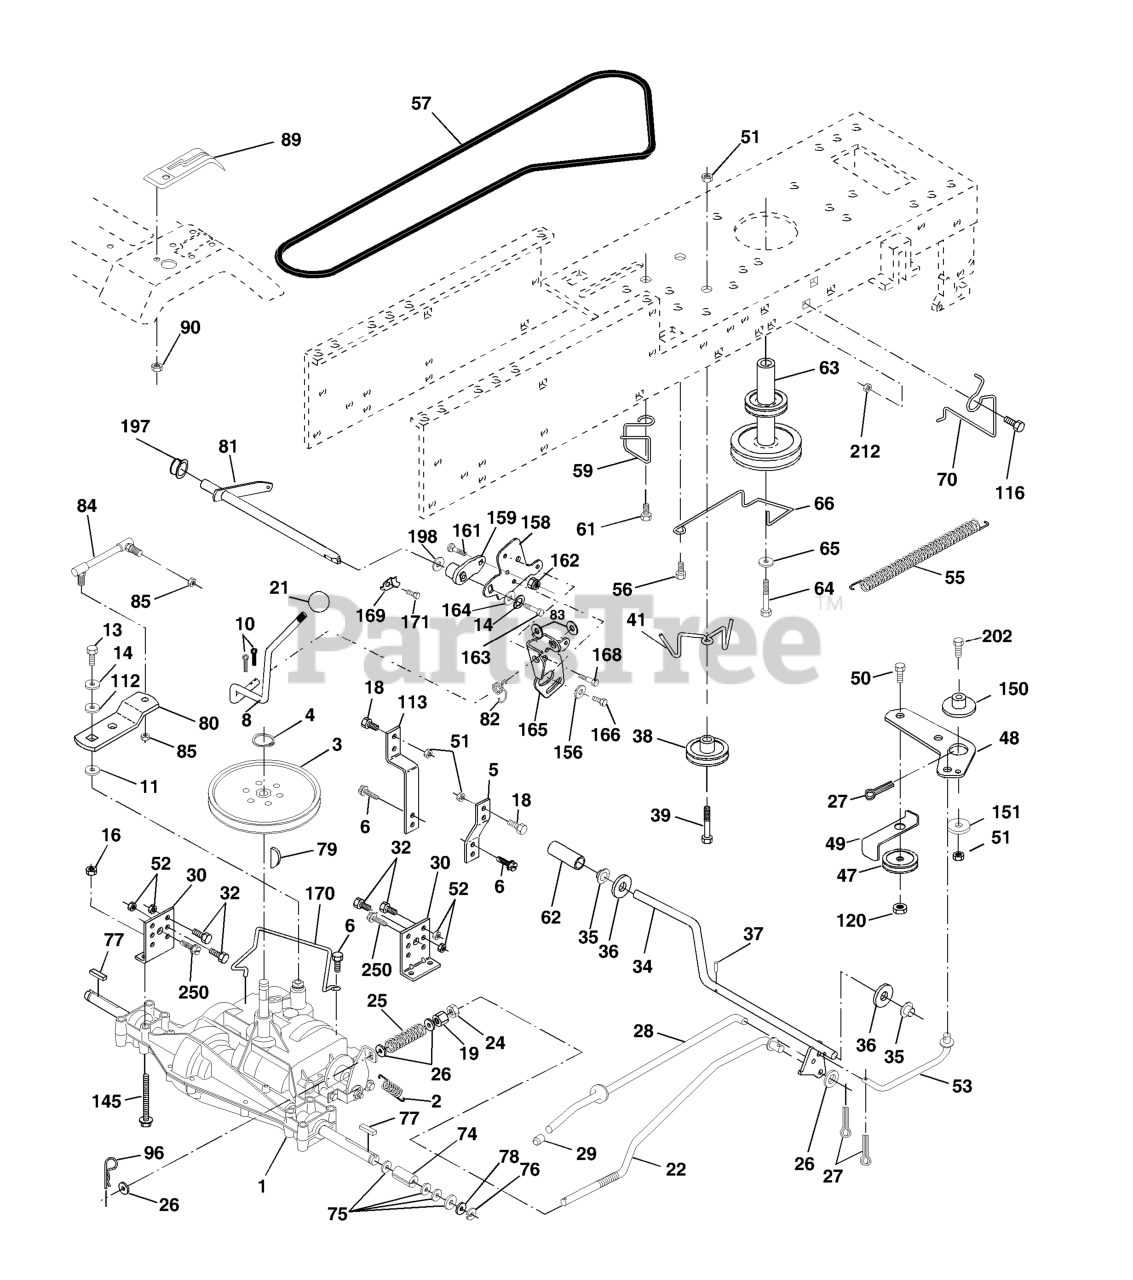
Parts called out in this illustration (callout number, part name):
2	SPRING,BRAKE RETURN
3	PULLEY TRANS
4	RETAINING RING LT
5	STRAP TORQUE
6	SCREW 5/16"
8	ROD.SHIFT.FENDER.ADJ.LT.CRD
10	PIN COTTER
11	WASH-SHFT PLT LT
13	BOLT 1/4-28X3/4
14	LOCKWASHER
16	NUT.71038.31-18.HEX.NYLOCK
18	BOLT
19	NUT
21	KNOB T (1/2-HOLE)
24	NUT
25	SPRING ROD LT
26	WASHER
27	COTTER PIN
28	ROD, PARKING BRAKE
29	PLUNGER CAP
30	BRKT, MOUNT TRNSAXLE
32	BOLT
34	SHAFT, FOOT PEDAL
35	BEARING.NYLON
36	WASHER LT
37	DRIVE PIN
38	PULLEY IDLER COMPOSITE
39	BOLT
41	KEEPER, BELT IDLER
47	IDLER PULLEY
48	BELLCRANK, CLUTCH
49	RETAIN BELT
50	BOLT
52	LOCKNUT
53	LINK, CLUTCH LT
55	SPRING, RETURN LT
56	SCREW.3/8-16
57	V-BELT
59	KEEPER, BELT CENTER
61	SCREW 3/8-16X.875
62	PEDAL COVER T
63	ENGINE PULLEY
64	BOLT
65	LOCKWASHER
66	KEEPER BELT ENGINE
70	KEEPER BELT ENG
74	SPACER AXLE
77	SQUARE KEY
79	KEY STD (1373) DANA
81	SHAFT ASM CROSS TAPERED
82	SPRING,TORSION
83	WASHER
84	LINK.TRNSAXLE
85	NUT LOCK CENTER 1/4 -28 FNTHD
89	CONSOLE, SHIFT STLT
90	NUT.PUSH.3/16
96	RETAINER M
112	WASHER LT
113	STRAP TORQUE LH LT
116	BOLT D
120	NUT LOCK FLG 3/8-16 UNC
145	BOLT
150	SPACER, RETAINER
151	WASHER 12/32X2X10GA
156	WASHER.SRRTD.5/16
158	BRACKET
159	HUB
161	BOLT
162	NUT.CROWNLOCK.1/4
163	BOLT
164	Washer 5/8 x .281 x 10 Ga
165	RP BRACKET
168	BOLT.SHOULDER.5/16-18X
169	PLATE FASTENING LT
170	KEEPER BELT T/A
171	SCREW LT
197	NYLINER SNAP 5/8" ID
198	WASHER.NYL.7/8IDX.105"HYD CR
212	NUT
250	SCREW 3/8-16X3/4
